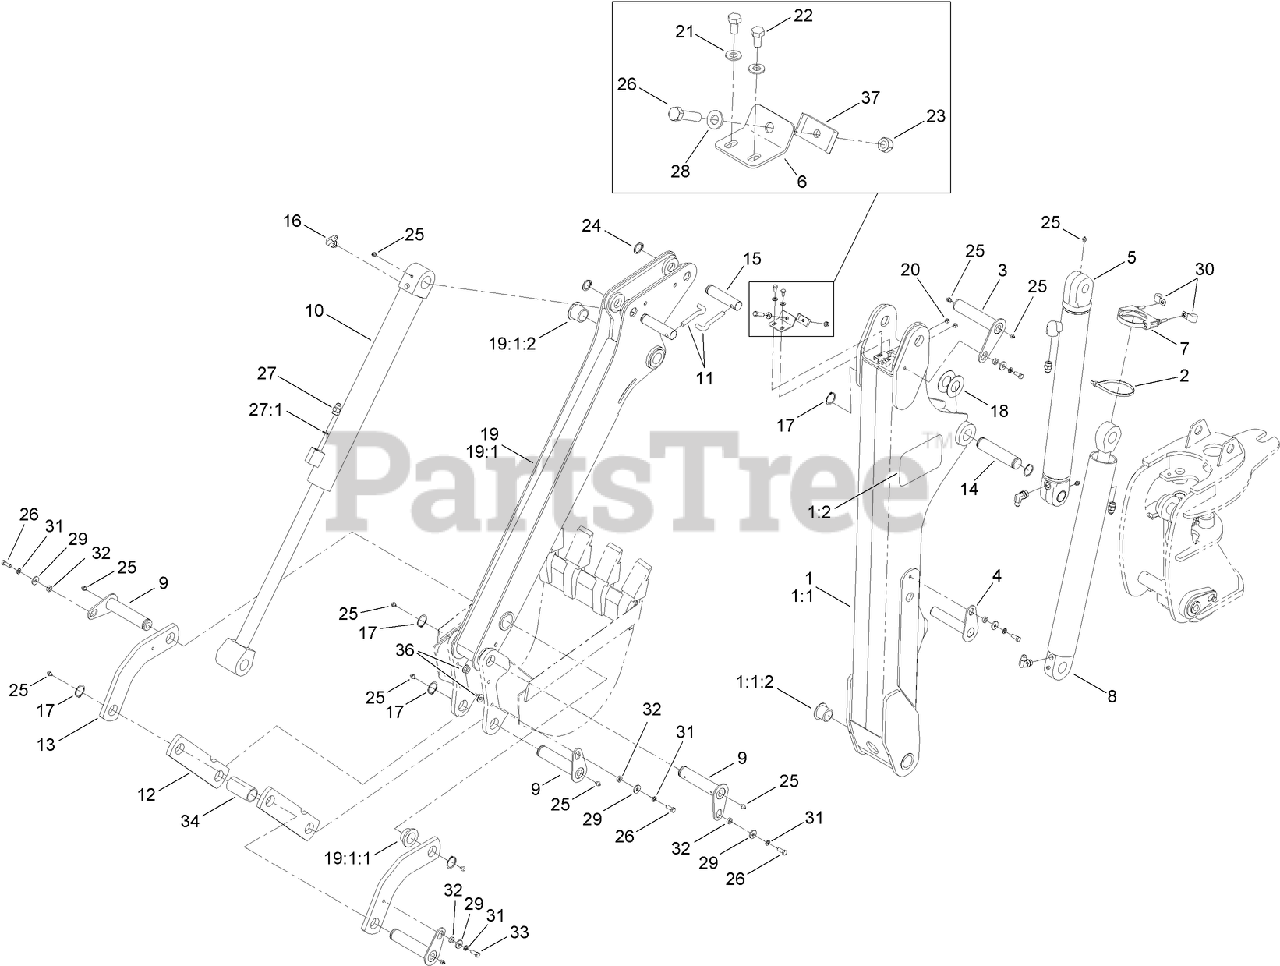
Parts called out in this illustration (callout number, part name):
1	BOOM ASM
1:1	BOOM
1:1:2	BUSHING-PIVOT, BOOM
2	TIE-CABLE
3	PIN-RETAINING
4	PIN-DIPPER CYLINDER TO BOOM
5	HYD CYLINDER ASM (DIPPER)
8	HYD CYLINDER ASM
10	HYD CYLINDER ASM (BUCKET)
11	PIN-RETAINER
12	LINK-STRAIGHT
13	LINK-CURVED
16	ELBOW-90 DEG
17	RING-RETAINING, EXTERNAL
19	DIPPER ASM
19:1	DIPPER
19:1:1	BUSHING-PIVOT, BUCKET
19:1:2	BUSHING
20	NUT-SQUARE
21	WASHER-PLAIN
22	SCREW-HH
23	NUT-HEX
24	RING-RETAINING, EXTERNAL
25	FITTING-GREASE
26	SCREW-HH
27	FITTING-STRAIGHT
27:1	O-RING
28	WASHER-FLAT
29	WASHER
30	CLAMP-R
31	WASHER-LOCK
33	SCREW-HH
34	SPACER-Bucket Links
36	NUT-HF, NI
37	CLAMP-TUBE
